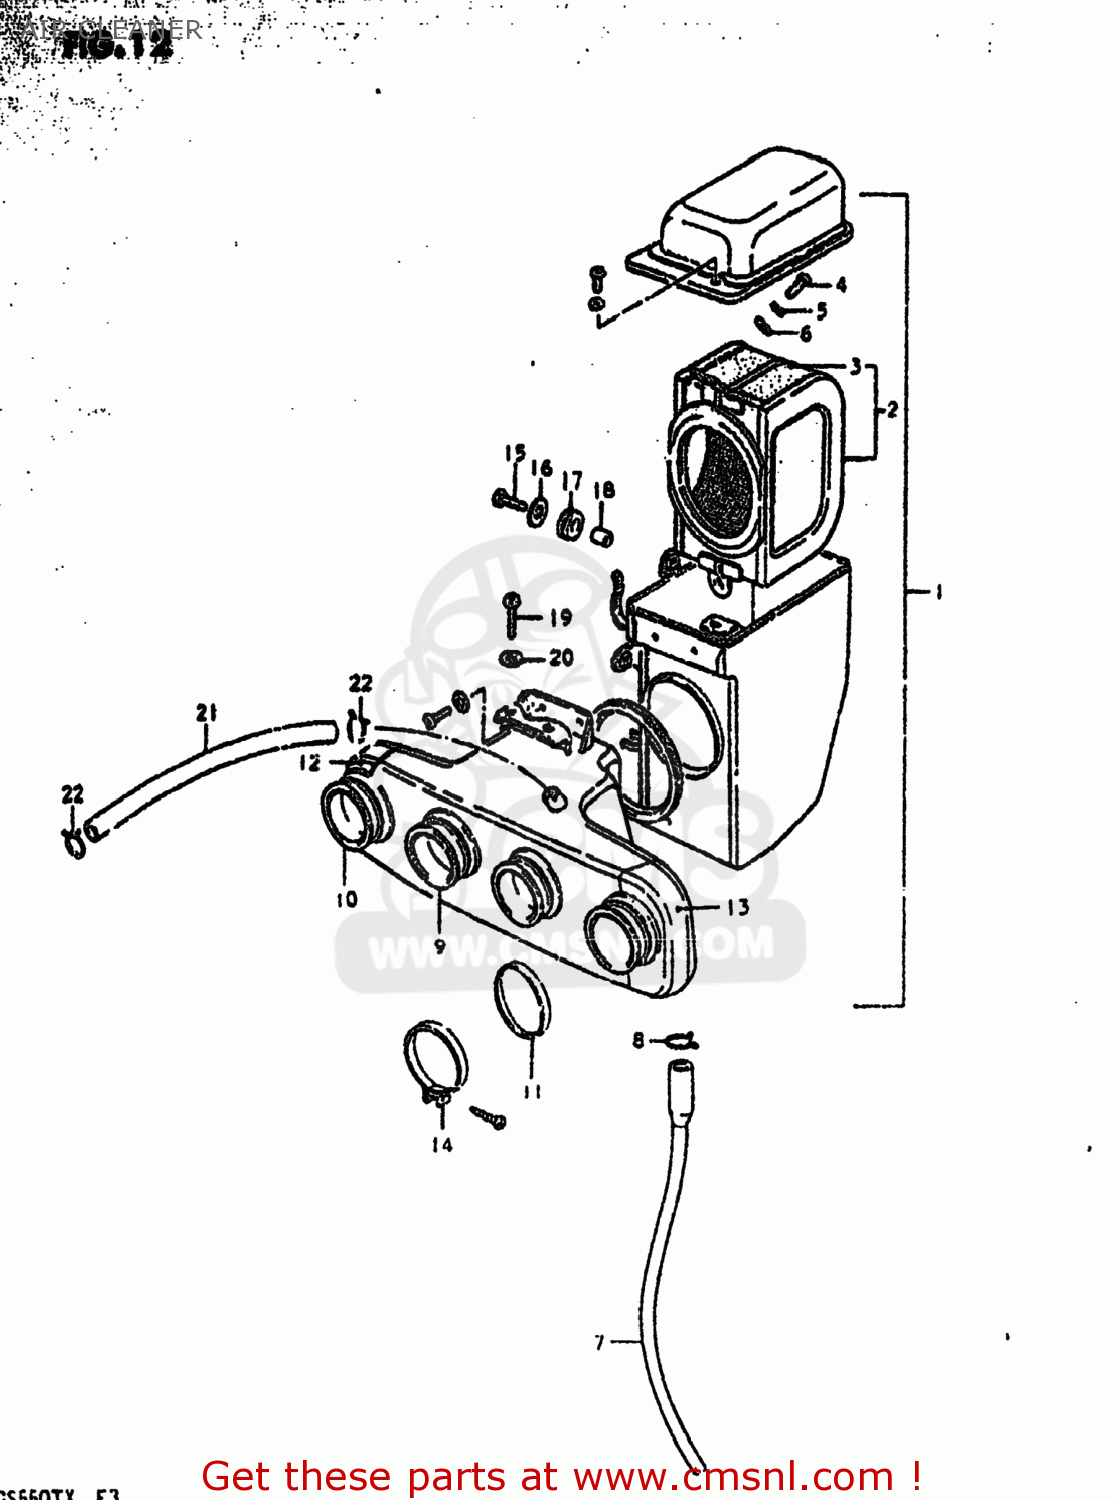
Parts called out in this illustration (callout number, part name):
1	CLEANER ASSEMBLY,AIR
2	FILTER ASSY
3	FILTER
4	SCREW
5	LOCK WASHER
6	WASHER
7	DRAIN TUBE
8	CLIP
9	TUBE,AIR CLEANER OUTLET A
10	TUBE,AIR CLEANER OUTLET B
11	RING,CARBURETOR AIR INLET HOSE
12	CLAMP
13	BOLT
14	WASHER
15	CUSHION
16	SPACER (6.1X9X9)
17	SCREW 6X12
18	WASHER
19	HOSE
20	CLIP
